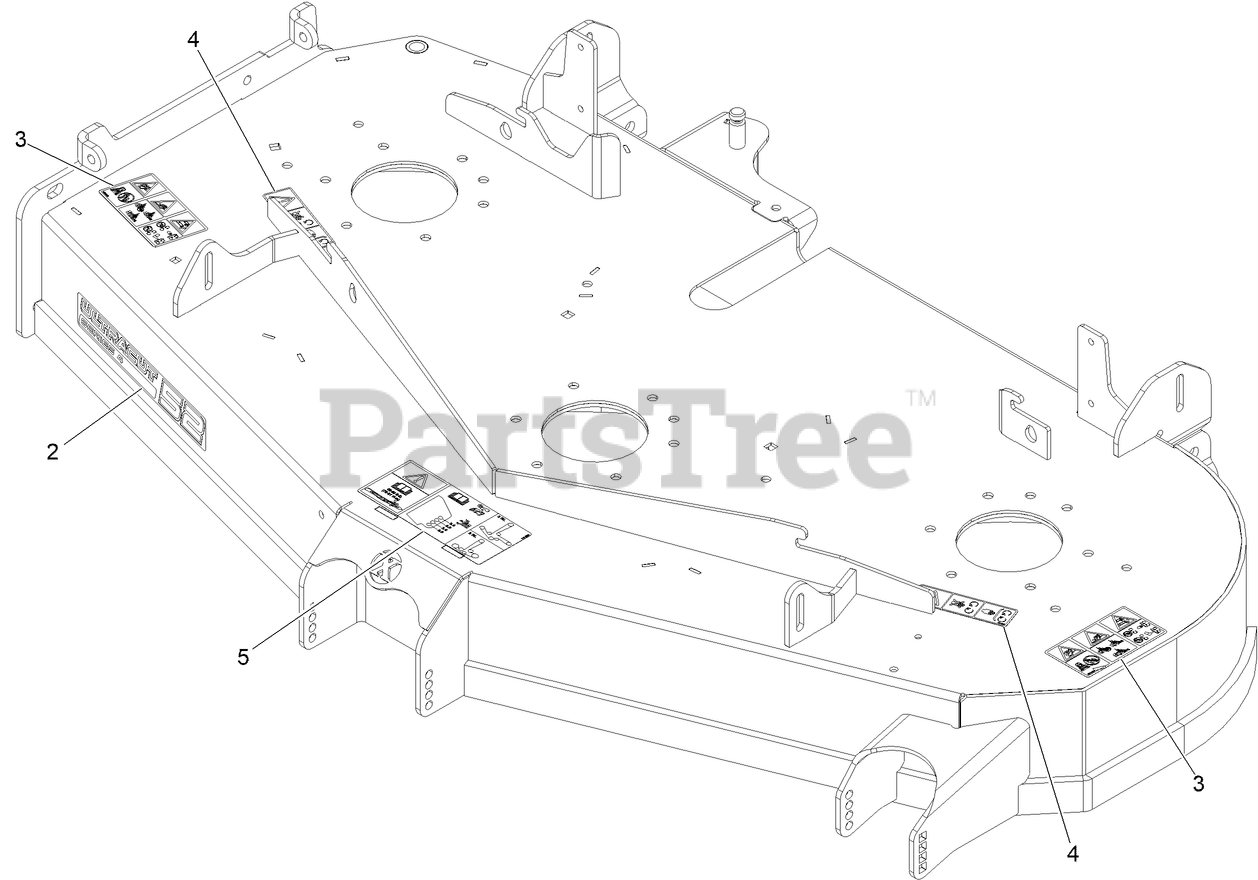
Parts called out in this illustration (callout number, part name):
2	DECAL, 524
3	DECAL-DANGER THROWN OBJECTS
4	DECAL-COVER, MISSING
5	Decal-Anti-Scalp-Belt Routing
